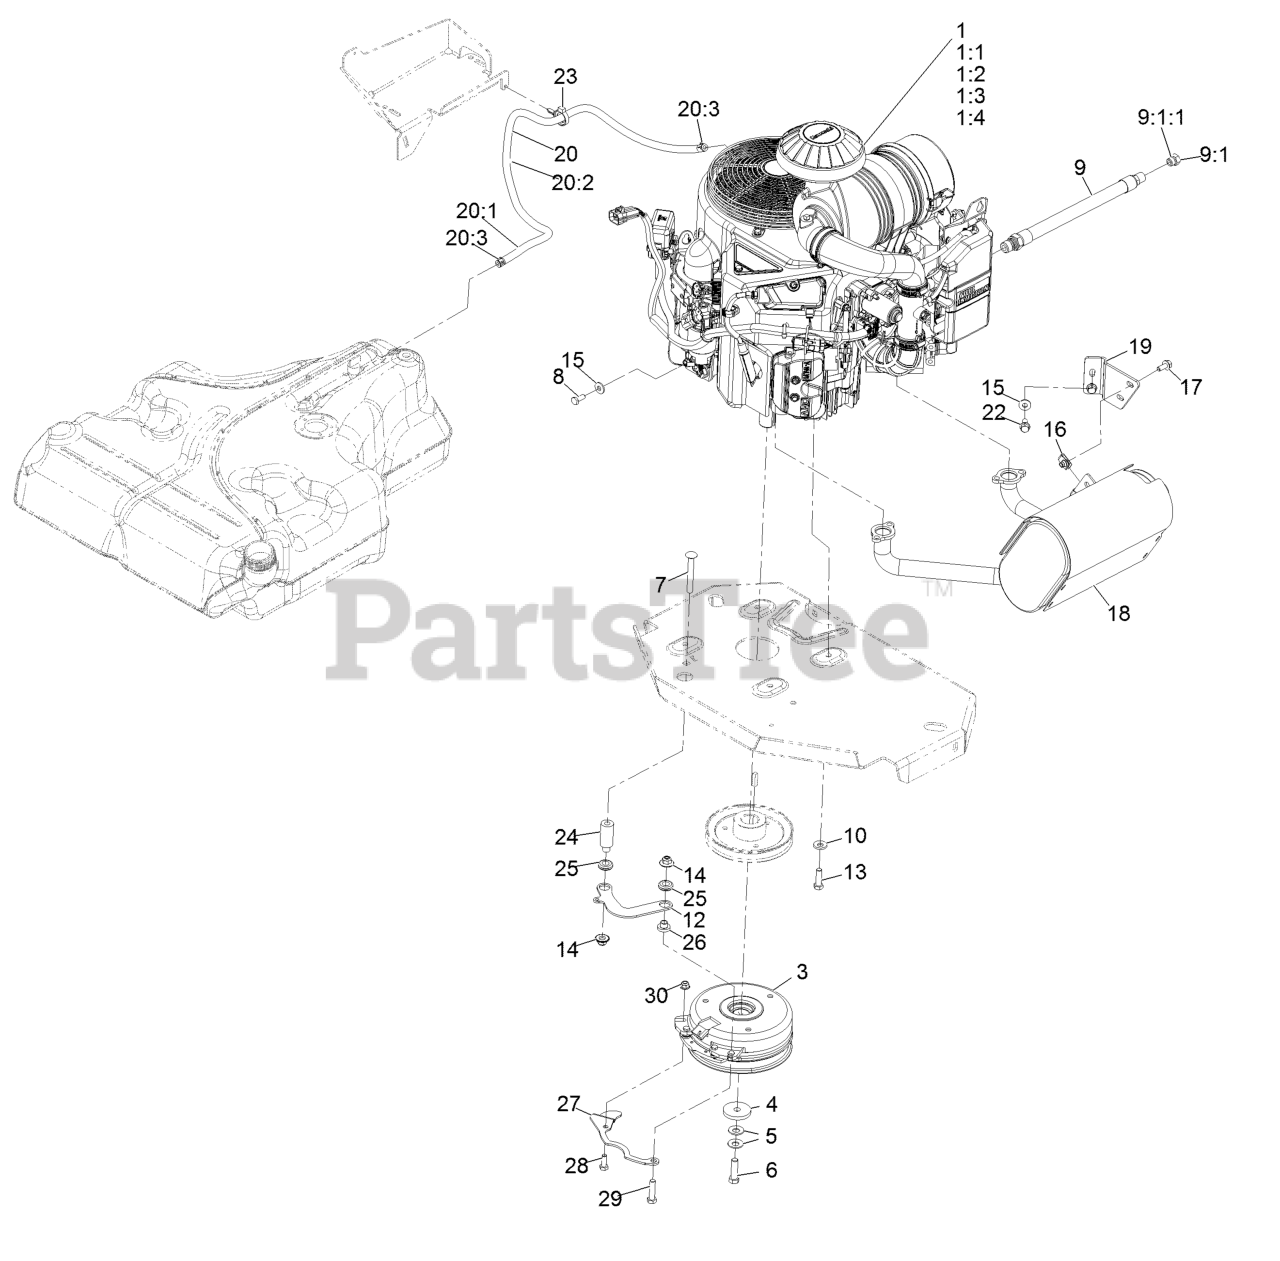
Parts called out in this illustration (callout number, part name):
1:1	Kawasaki 49065-2078 Engine Oil Filter
1:2	Kawasaki 49019-0031 Fuel Filter
1:3	Kawasaki 11013-7039 Safety Filter
1:4	Kawasaki 11013-7038 Air Filter
3	Clutch Kit
4	Washer-Clutch
5	Washer-Spring Disc 7/16
6	Screw-HH 7/16-20 X 1 1/2 W/Loctite
7	Bolt-Carriage 3/8-16 X 3
8	Screw-HH M8-1.25 X 20Mm
9	Asm-Hose Oil Drain W/Plug
9:1	Plug-W/O-Ring
9:1:1	O-Ring
10	Washer-Spring Disc 3/8
12	Link-Anchor, Clutch
13	Screw-HH 3/8-16 X 1 1/4
14	Nut-Nyloc 3/8-16 Flg
15	Washer-Spring Disc 5/16
17	Screw-HH Flg 5/16-18 X 3/4
18	Muffler
19	Bracket-Muffler
20	Fuel Line ASM
20:1	Hose-Fuel Line 38 1/4"
20:2	Sleeve-Thermal
20:3	Clamp-Hose
22	Screw-HH M8-1.25 X 20Mm
23	Clamp-Hose
25	Grommet-Rubber
27	Belt-Guide
28	Screw-HH 5/16-18 X 7/8
29	Screw-HH 3/8-16 X 1 1/2
30	Nut-Nyloc 5/16-18 Flg
